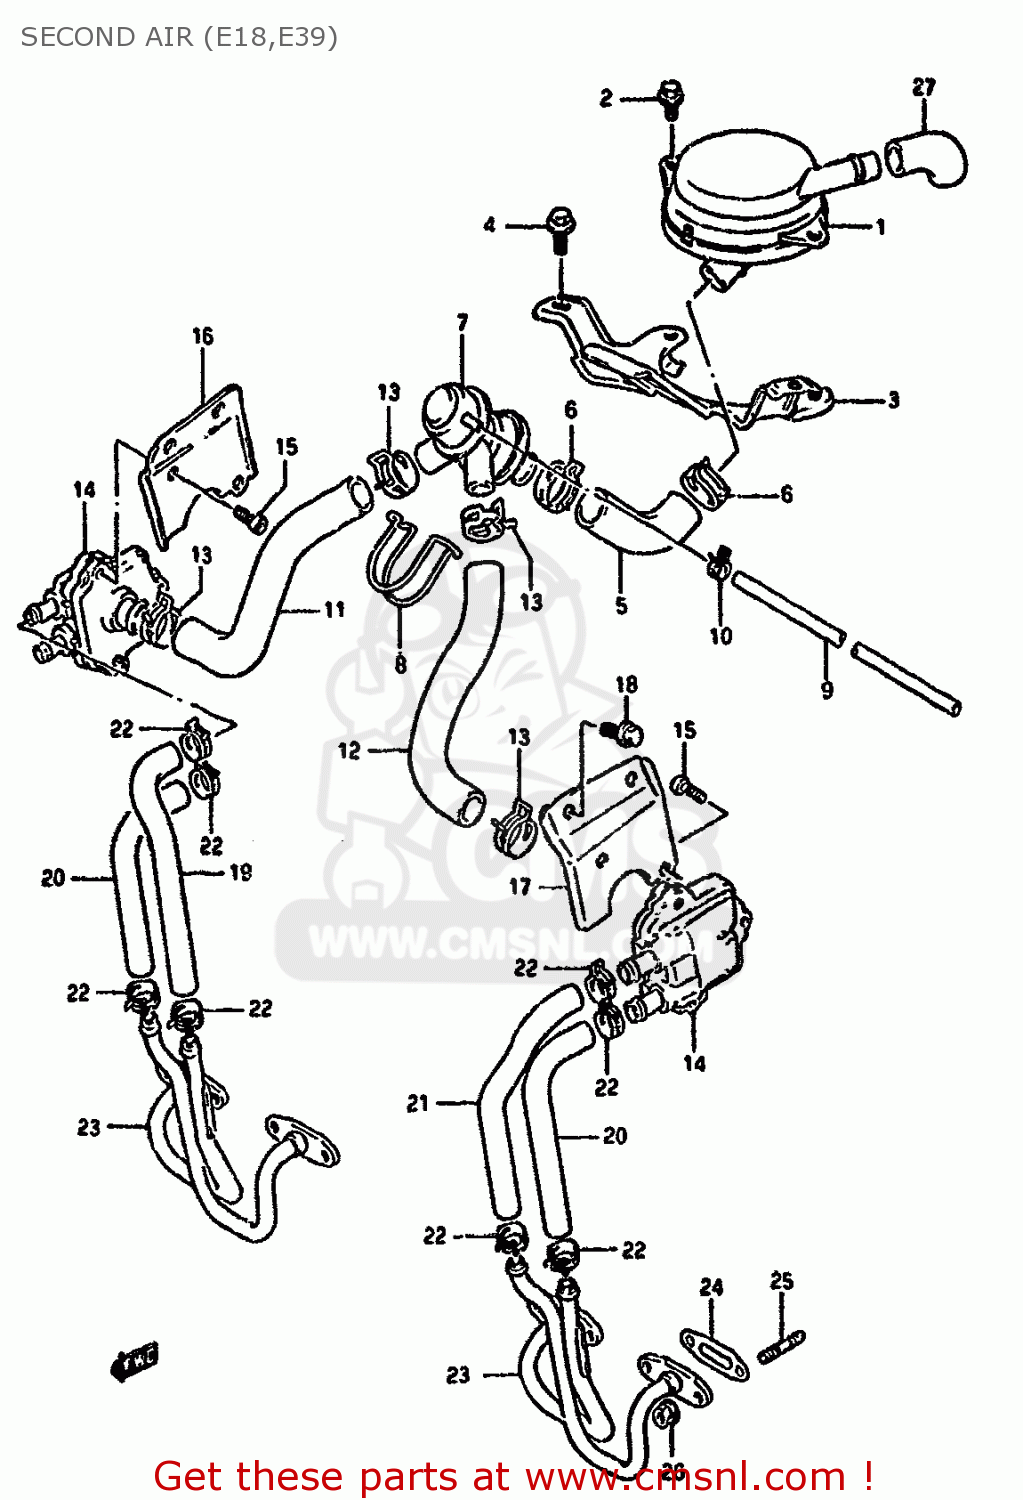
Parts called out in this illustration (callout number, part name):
1	CLEANER ASSEMBLY,SECOND AIR
2	BOLT
3	BRACKET COMP,SECOND AIR C
4	BOLT
5	HOSE,SECOND AIR NO.3
6	CLIP
7	VALVE ASSY,2ND AIR SWITCHING
8	CLAMP,SWITCHING VALVE
9	HOSE
10	CLAMP
11	HOSE,SECOND AIR NO.2,RIGHT
12	HOSE,SECOND AIR NO.2,LEFT
13	CLIP
14	VALVE ASSY,2ND AIR REED
15	BOLT
16	BRACKET,SECOND AIR REED VALVE
17	BRACKET,SECOND AIR REED VALVE
18	BOLT
19	HOSE,SECOND AIR NO.1,RIGHT,INLET
20	HOSE,SECOND AIR NO.1,OUTLET
21	HOSE,SECOND AIR NO.1,LEFT,INLET
22	CLIP
23	PIPE,2ND AIR,L
24	GASKET,SECOND AIR PIPE (NAS)
25	STUD BOLT
26	NUT
27	HOSE,SECOND AIR CLEANER
